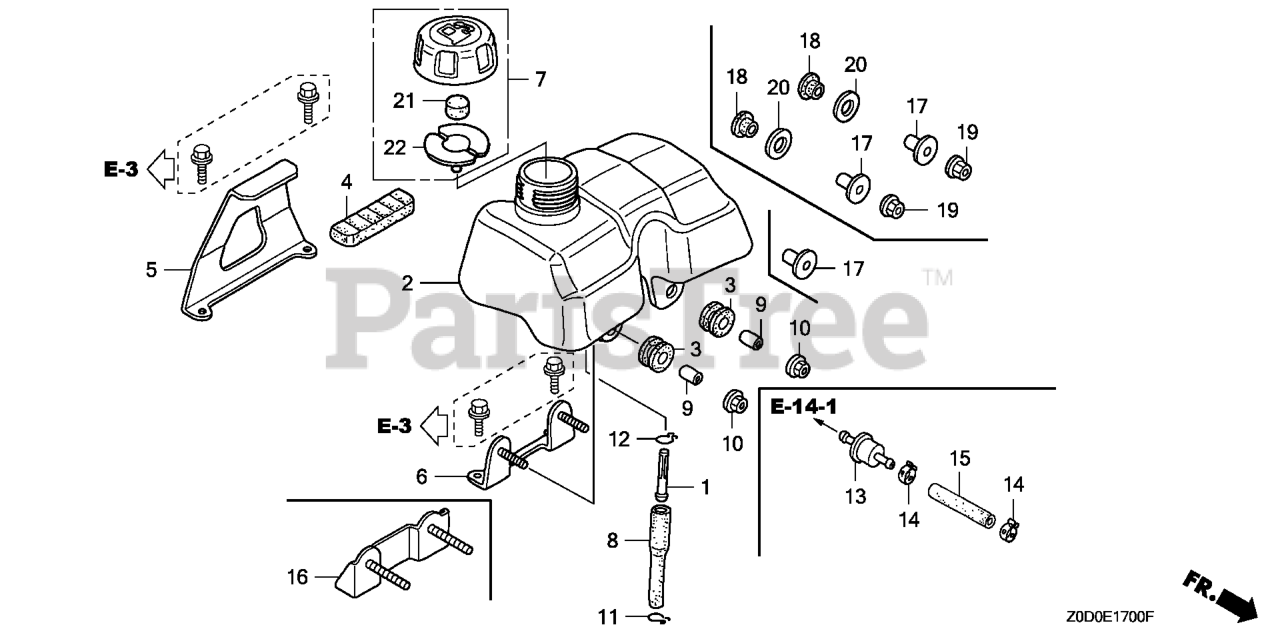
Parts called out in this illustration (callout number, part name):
13	FILTER, FUEL
14	CLIP, TUBE (D8.5)
15	BULK HOSE, FUEL (4.5X3000) (4.5X120)
